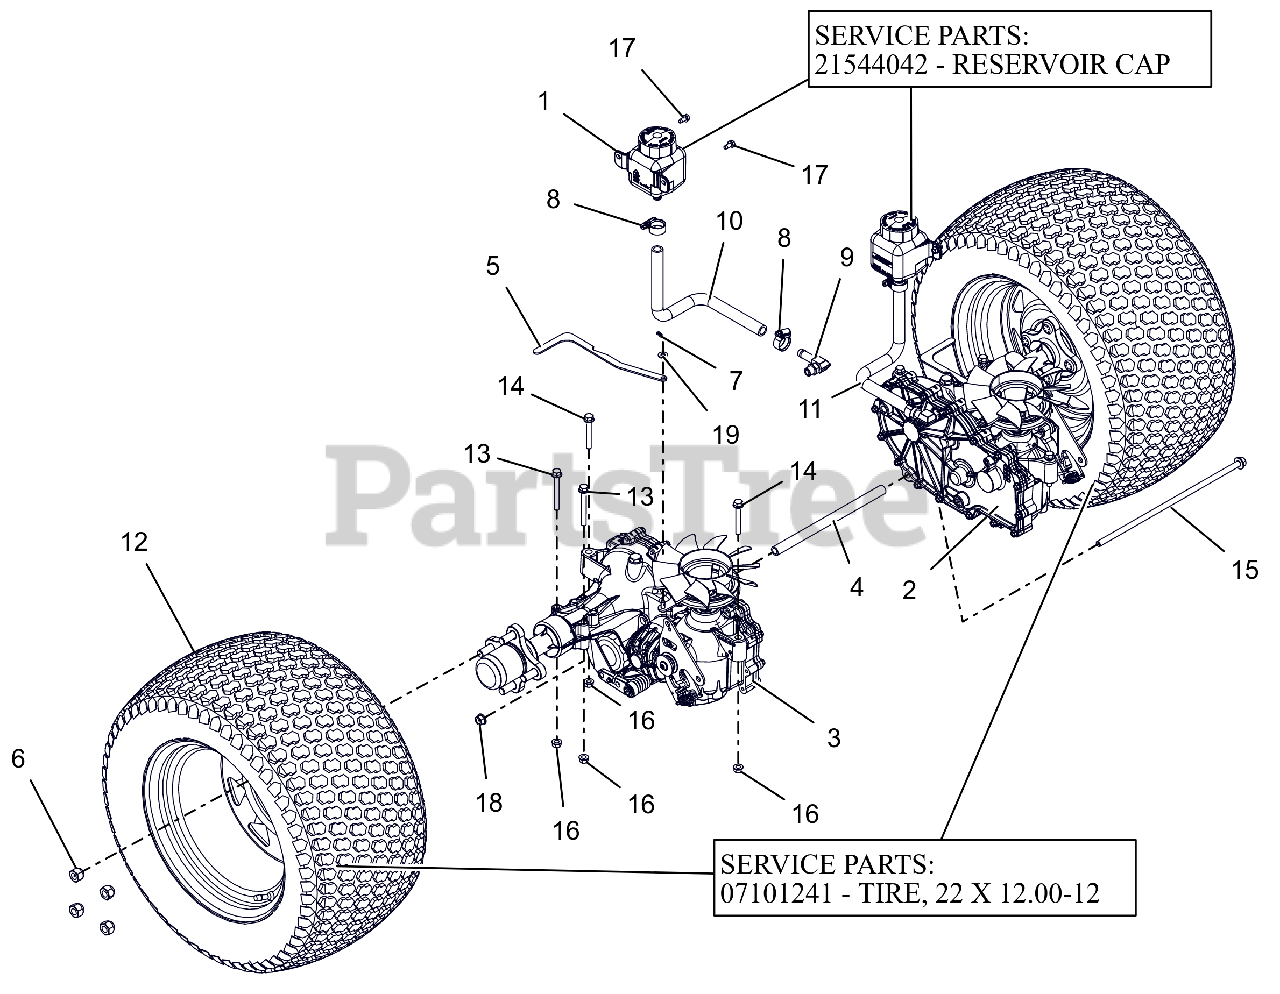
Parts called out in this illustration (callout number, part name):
1	TANK, EXPANSION
1	CAP, HYDRO RESERVOIR REPLAC.
2	TRANSAXLE, ZT3100 LH
3	TRANSAXLE, ZT3100 RH
4	SPCR, TRANSAXLE .406 ID X .630 OD X 9.95LG (BLACK)
5	BRKT, VALVE DUM
6	NUT, WHEEL .50-20 ZCC
7	PIN, HAIR #225 .072X1.09
8	CLAMP,.88 DIA. HOSE
9	FITTING, HYD (90 DEG)
10	HOSE, FORMED EXPANSION -HD RH
11	HOSE, FORMED EXPANSION -HD LH
12	ASM, WHL/TIRE 22X12.00-12 K500
12	TIRE, 22X12.00-12
13	BLT,HEX-FLG .31-18X2.75 G5 ZCC
14	BLT,HEX-FLG .31-18X2.25 G5 ZCC
15	BLT, HEX-FLG 0.375-16X13 GR5 ZC120
16	NUT,LK-CTR-FLG .31-18 GF ZCC
17	SCR-TAP .25-20X.50 HWH ZCC
18	NUT-LK-CTR-FLG .375-16 GF ZCC
19	WSHR,FLT .281X.625X.065 ZCC
